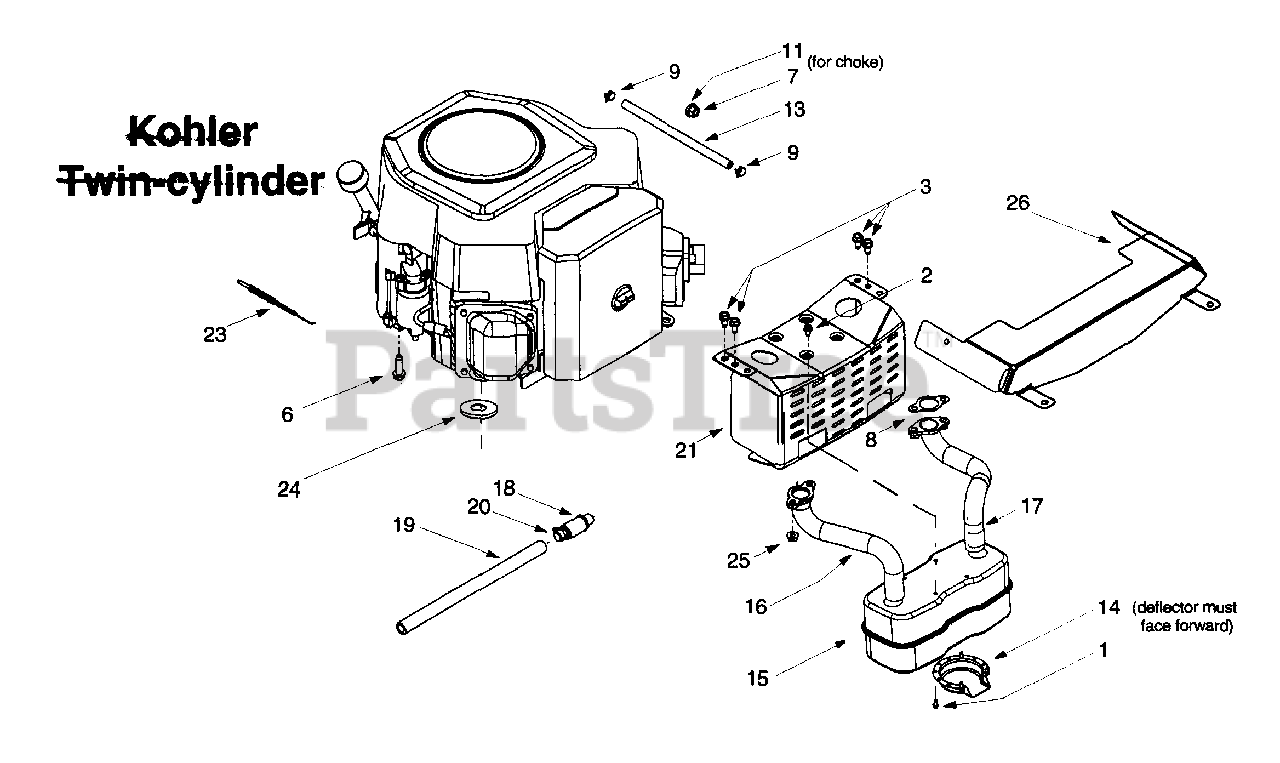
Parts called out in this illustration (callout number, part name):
1	Self Tapping Screw, #8-32 x .375
2	Self Tapping Screw, 1/4-20 x .5
3	Self Tapping Screw, 5/16-18 x .625
6	Self Tapping Screw, 3/8-16 x 1.25
7	Hex Nut, 3/8-16
8	Exhaust Gasket
9	Hose Clamp
11	Lock Washer, 3/8 x .56 x .018
13	Fuel Line Hose
14	Muffler Deflector
15	Muffler
16	RH Exhaust Pipe
17	LH Exhaust Pipe
18	Oil Drain Valve
19	Oil Drain Hose
20	Oil Drain Cap
23	Throttle Cable
24	Flat Washer, 1.0 x 1.56
25	Flange Nut, M8 x 1.25-6
26	Heat Shield
